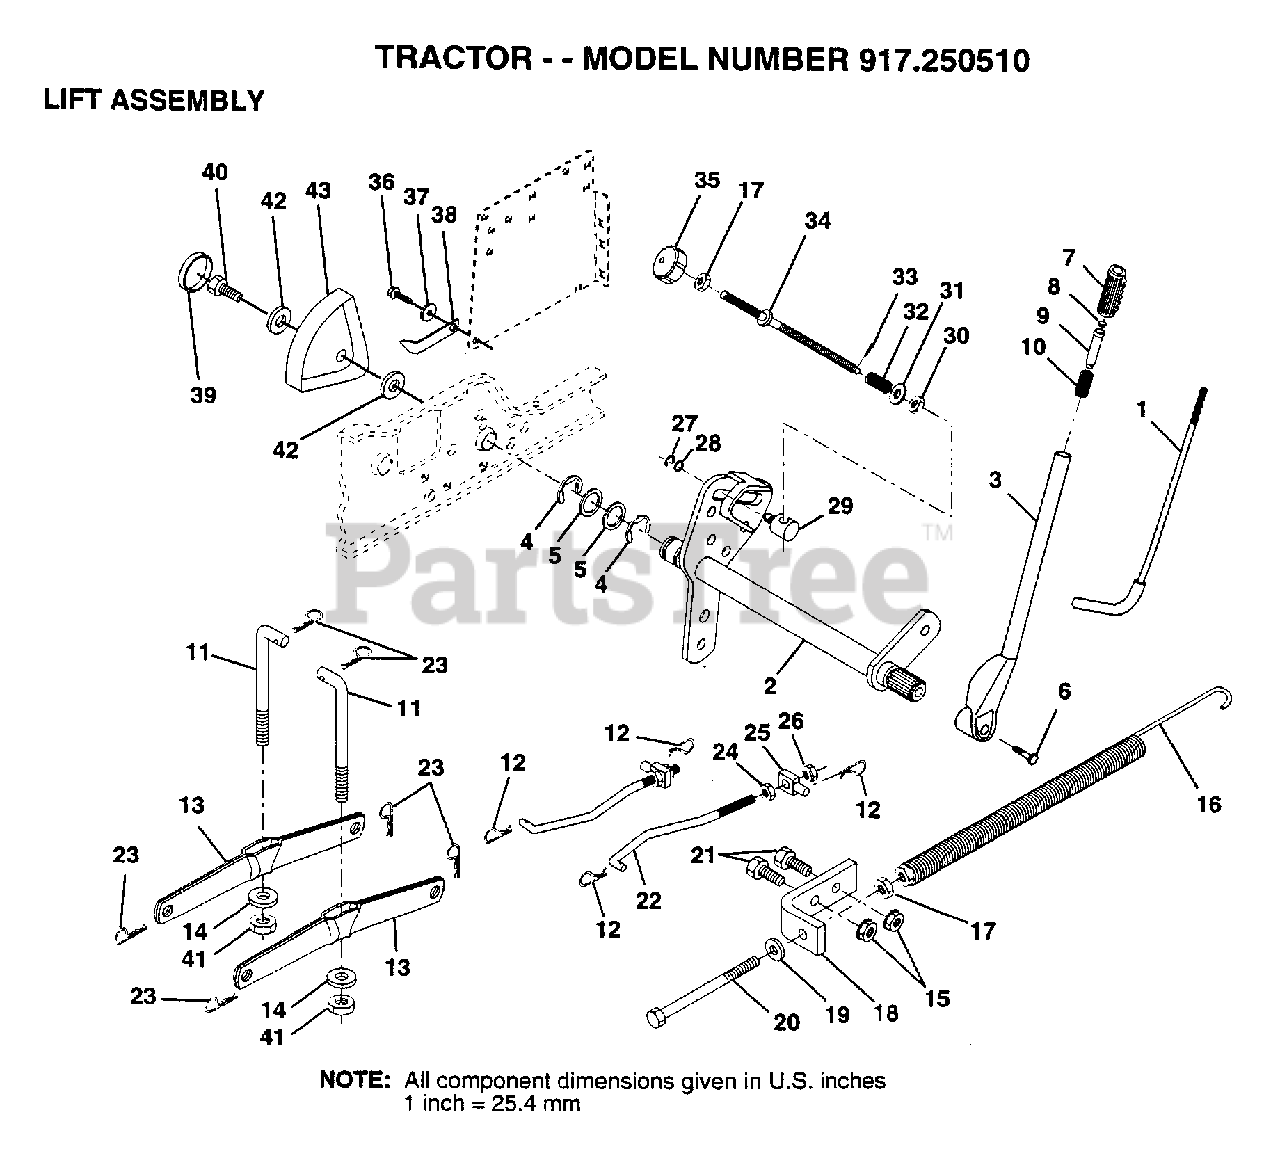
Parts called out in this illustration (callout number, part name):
1	LEVER ROD LT
4	E-RING
5	WASHER
6	"BOLT,HEX"
7	GRIP HANDLE
10	SPRING T
12	RETAINER.SPRING
13	ARM SUSP REAR
14	BEARING PVT LH
18	BRACKET SPRING AS
19	WASHER
20	BOLT-ADJ SPRING T
21	BOLT
22	LINK.FRONT
24	NUT
25	TRUNION
26	NUT.LK.W/WSH.1/2.
27	KLIP RING
28	WASHER
29	TRUNION LT
30	NUT T
31	WASHER
32	SPRING.COMP.INF.H
34	ROD.ADJ.LIFT
35	KNOB INF 3/8-16
36	SCREW
37	WASHER T
38	POINTER HGT IND
39	"PLUG,HOLE"
40	SCREW
41	NUT.CROWNLOCK.3/8
42	WASHER
43	HEIGHT INDICATOR
